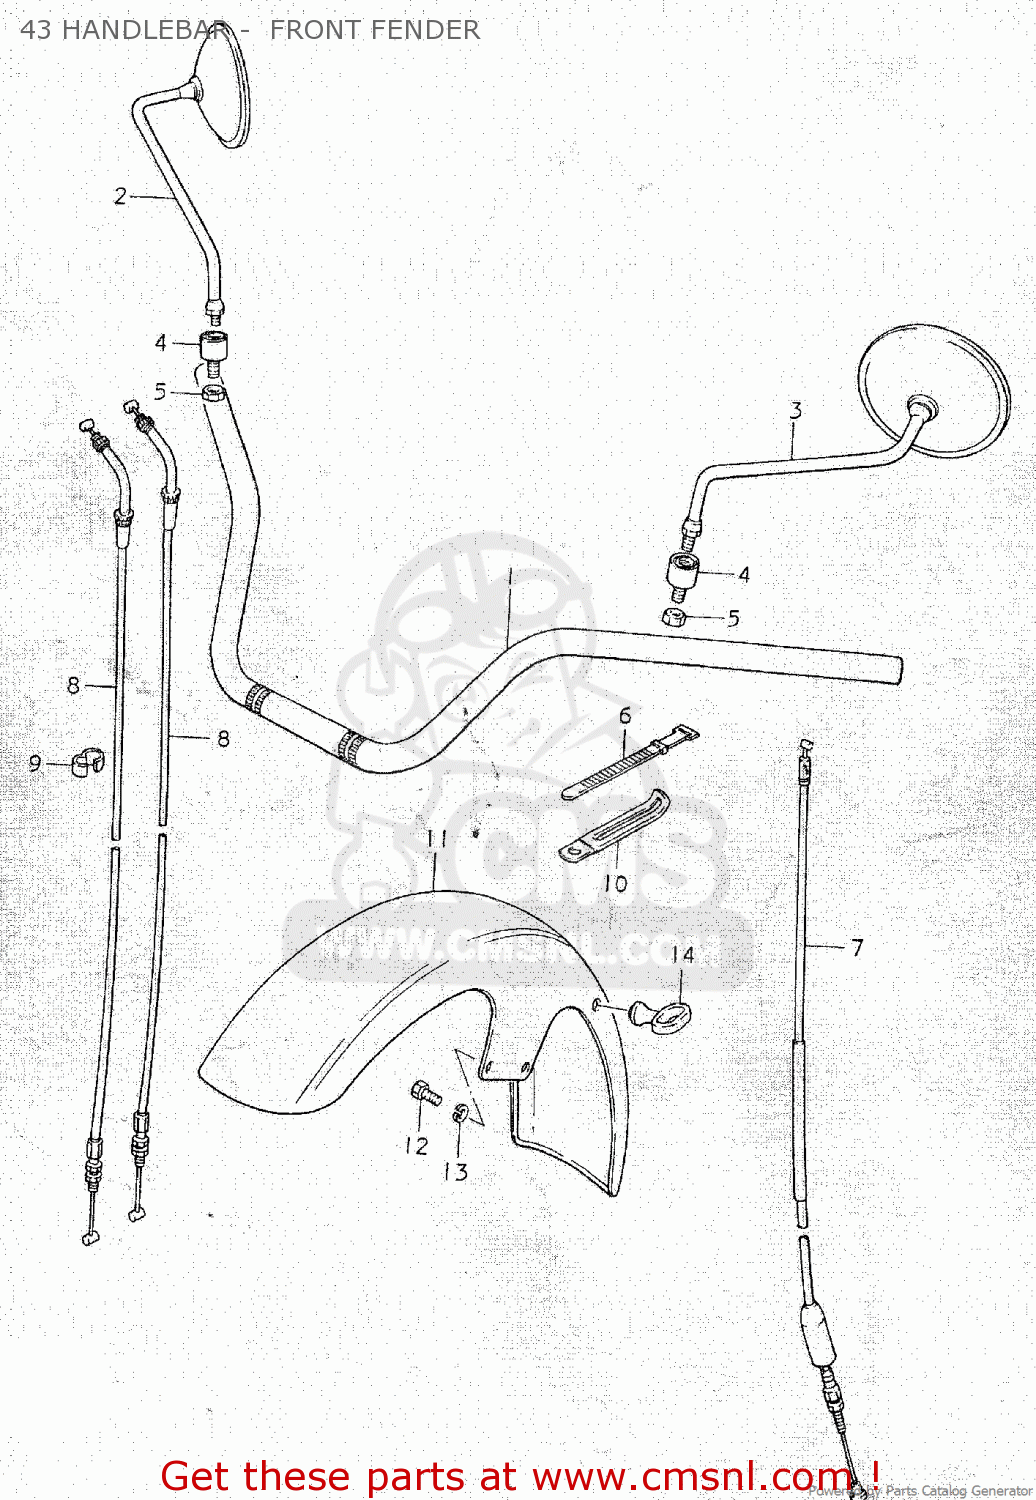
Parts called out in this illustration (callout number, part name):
1	STUUR
2	MIRROR ASSEMBLY,RIGHT
3	MIRROR ASSEMBLY,LEFT
4	CUSHION,REAR VIEW MIRROR
5	NUT
6	CLAMP(L:120)
7	CABLE ASSY,CLUTCH
8	CABLE ASSY,THROTTLE
9	CLIP
10	CLAMP
11	FENDER,FR
12	BOLT
13	LOCK WASHER
14	GUIDE,CABLE
